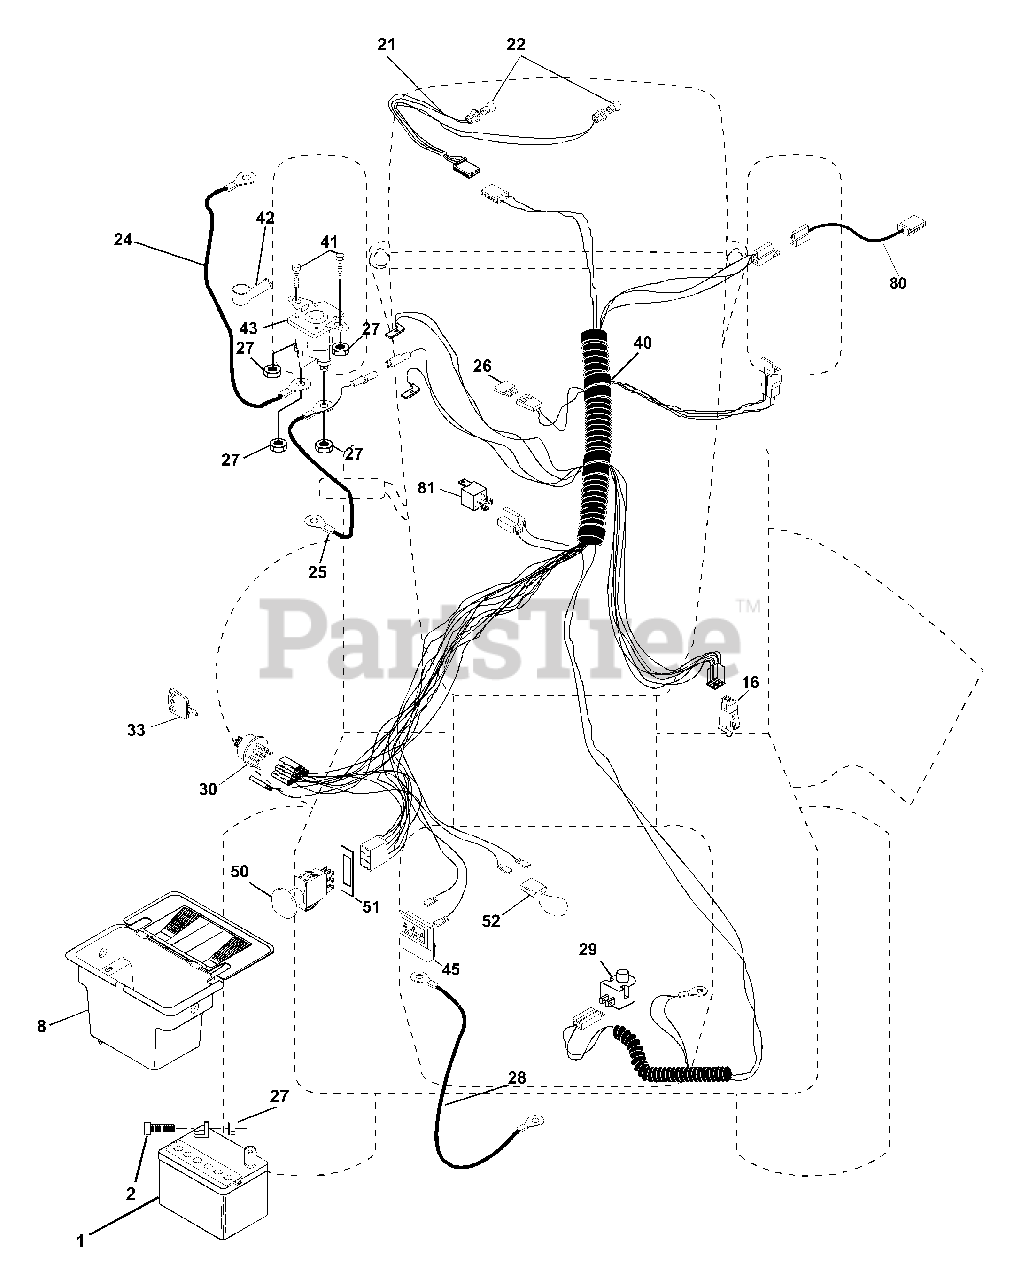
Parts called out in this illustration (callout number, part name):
1	Battery 12 Volt 25 AMP
2	Bolt Hex Hd 1/4-20unc x 3/4
8	Case Battery Mech Hinge
16	Switch Interlock Push-In
20	Nut Jam Hex 1/4-20 Unc
21	Harness Asm Light W/4152j
22	Bulb Light #1156
24	Cable Battery 6 Ga 11" red
25	Cable Battery 6 Ga 44" red w/16 wire
26	Fuse 15 AMP Auto Green
27	Nut Keps Hex 1/4-20 Unc
28	Cable Ground 6 Ga 12" black
29	Switch Plunger Normal OP Olive
30	Switch Ign
33	Key Ign Molded
40	Harness Ign.
41	Bolt Blk Fin Hex 1/4 - 20 x 1/2
42	Cover Terminal Red
43	Solenoid
45	Ammeter Rectangular 15 Amp
50	Switch PTO 3PDT Black Delta
51	Ring Retainer PTO
52	Protection Wire Loop
80	Harness Clutch EVX
